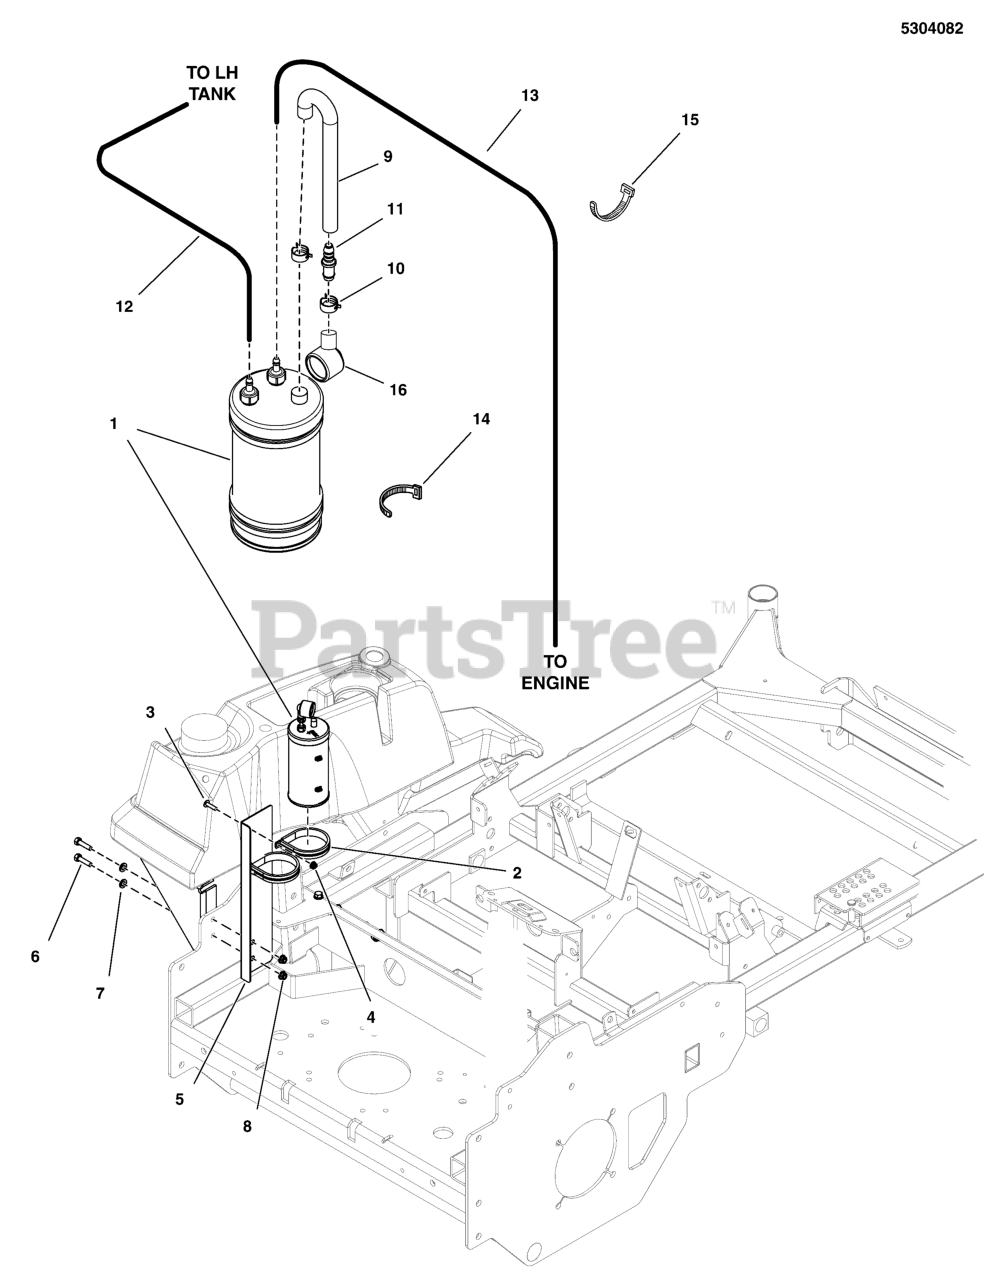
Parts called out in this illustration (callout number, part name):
1	CNSTR, CARB, 6 GAL
2	CLAMP, 3" ID, CUSHIONED, STAINLESS
4	NUT, 1/4-20 HEX NYLOCK FLANGE
5	PLATE, CARB CAN, S200XT, LH - BLK
6	BOLT, 5/16-18 X 1-1/4 GD5 CZ
7	WASHER, 5/16 LOCK CZ
8	NUT, 5/16-18 HEX NYLOCK FLANGE
9	HOSE, FORMED, EVAP CANISTER
10	CLAMP, HOSE
11	FITTING, STRAIGHT, 10MMX10MM, PLASTIC
12	HOSE, VAPOR, 5MM ID, 10.00 LG
13	HOSE, VAPOR, 5MM ID, 58.00 LG
14	TIE, SELF-LOCKING, 15"
15	TIE, SELF-LOCKING, 12"
16	DUST FILTER, CANISTER
